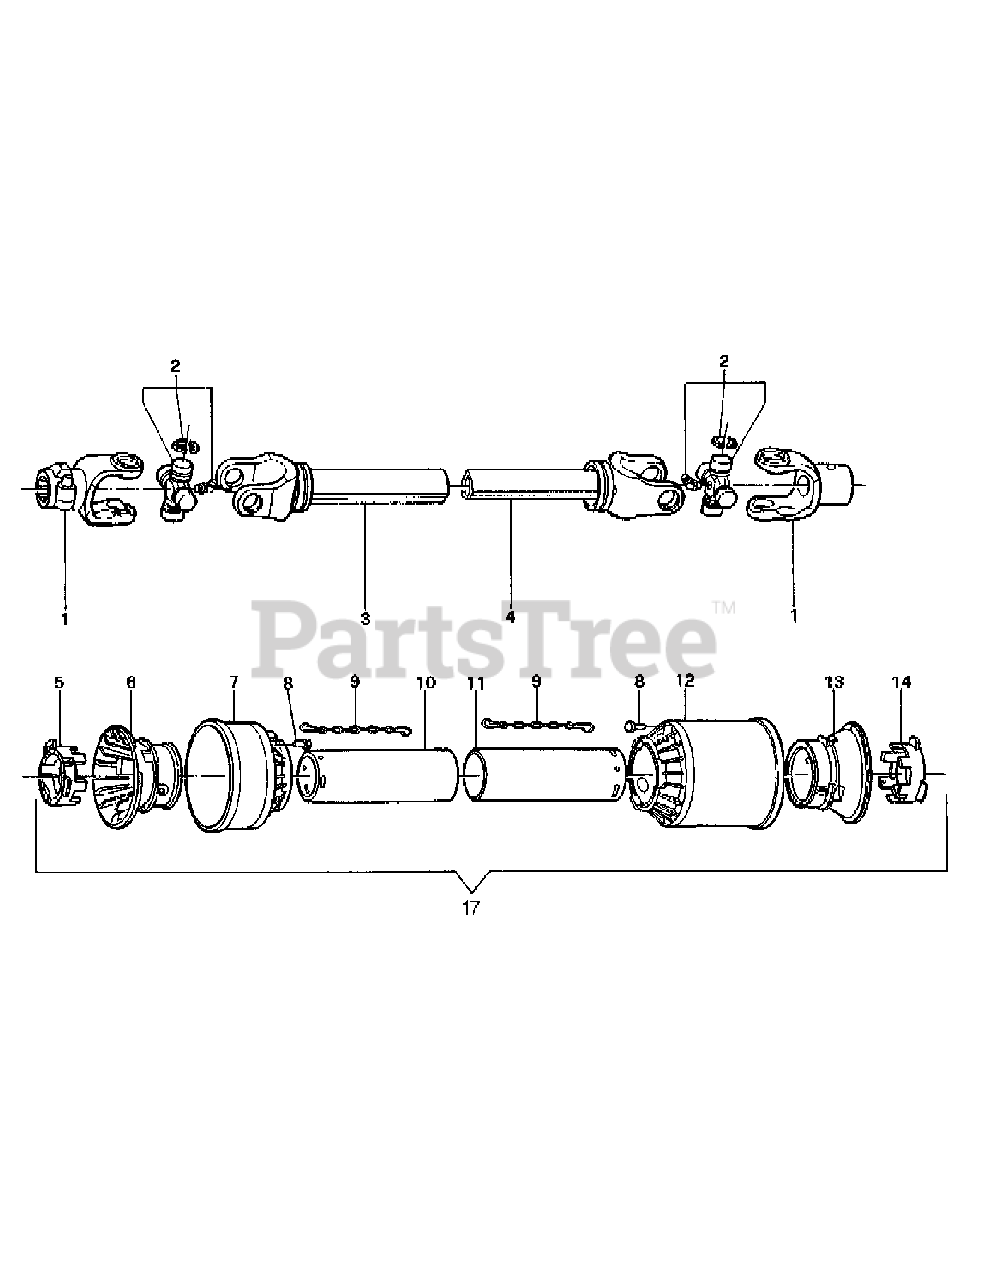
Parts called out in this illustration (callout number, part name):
2	Cross and bearing
3	Outer tube FM48
3	Outer tube FM60
3	Outer tube FM72
4	Inner tube FM48
4	Inner tube FM60
4	Inner tube FM72
5	Outer locking ring; # 1A169160 & below
6	Outer tube rigid cone; # 1A169160 & below
7	Outer cone; #1A169160 & below
8	Pin; #1A169160 & below
9	Chain
10	Female tube shield FM48; # 1A169160 & below
10	Female tube shield FM60; # 1A169160 & below
10	Female tube shield FM72; # 1A169160 & below
11	Male tube shield FM48; # 1A169160 & below
11	Male tube shield FM60; # 1A169160 & below
11	Male tube shield FM72; # 1A169160 & below
12	Outer cone (long); #1A169160 & below
13	Inner tube rigid cone; # 1A169160 & below
14	Inner locking ring; # 1A169160 & below
17	Complete shielding FM48; # 1A169160 & below
17	Complete shielding FM60; # 1A169160 & below
17	Complete shielding FM72; # 1A169160 & below
